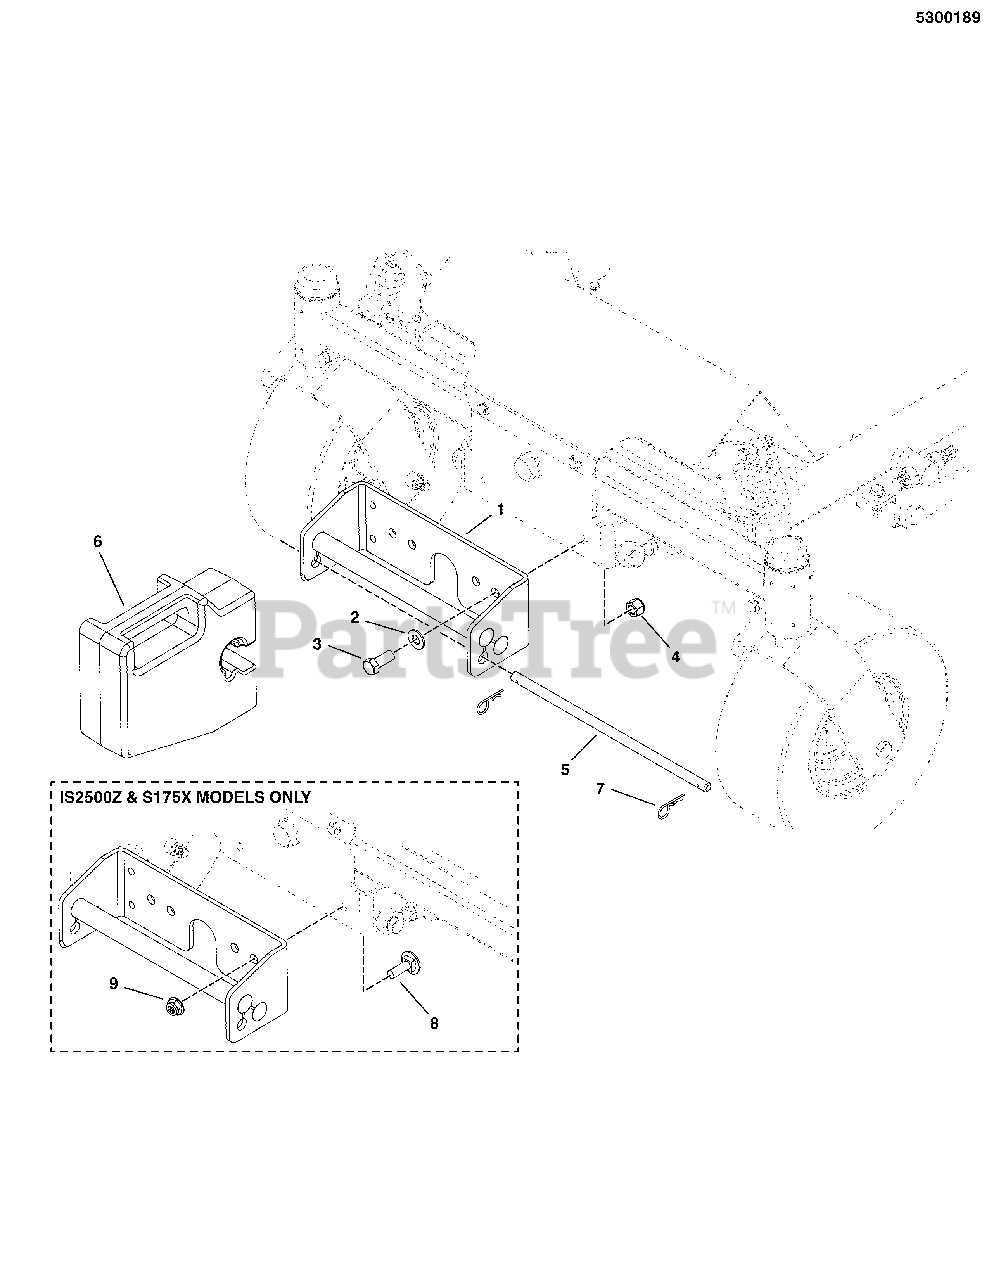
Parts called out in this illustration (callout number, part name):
1	HOLDER ASMY-WEIGHT CONS Z CAT - BLACK
2	WASHER, 1/2 SAE
3	BOLT, 1/2-20 X 1-1/4" GD5 CZ
4	NUT, Hex, Nylon Lock, 1/2-20
5	ROD-.500DIA 13.75LG YELLOW CON
6	WEIGHT-QUICK ATTACH 50LB SUITCASE PAINTED
6	WEIGHT-QUICK ATTACH 33LBS PAINTED BLACK
7	PIN, HAIR, .0915 X 1-7/8
8	BOLT, CARRIAGE 1/2-13 X 1-1/4 GD.5
9	NUT, Hex Flange, Nylock, 1/2-13
